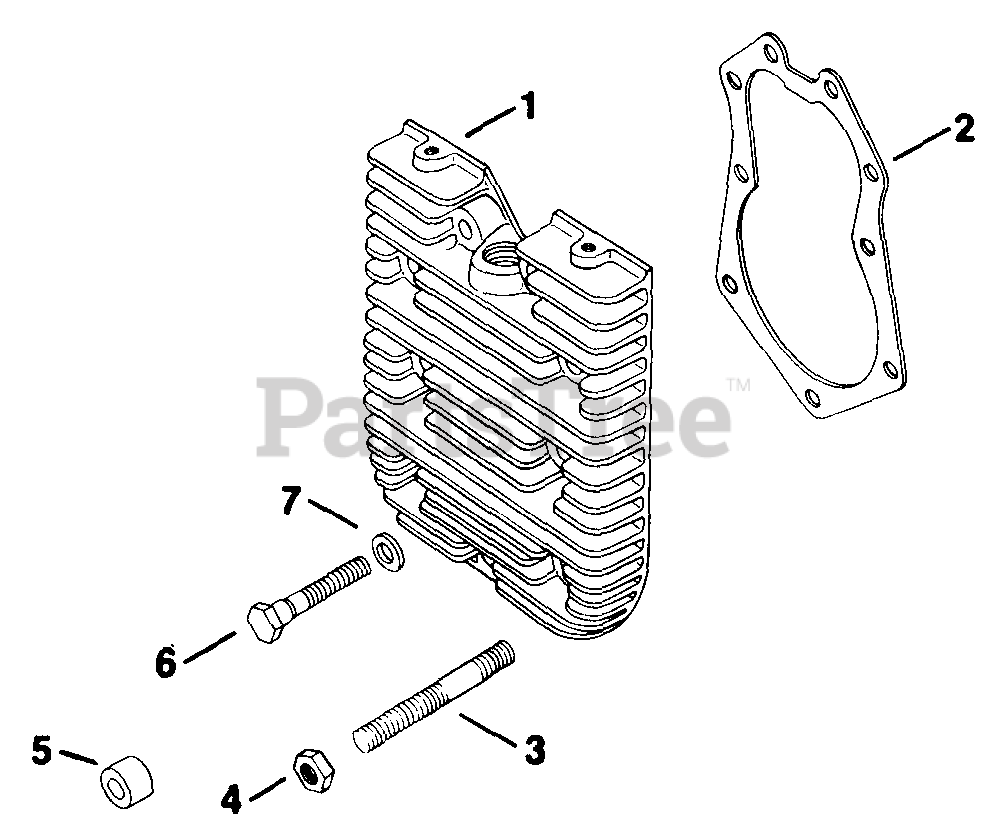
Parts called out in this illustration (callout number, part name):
1	HEAD - USE 52 015 08
2	GASKET - USE 52 052 04
7	WASHER, FLAT 5/16"
